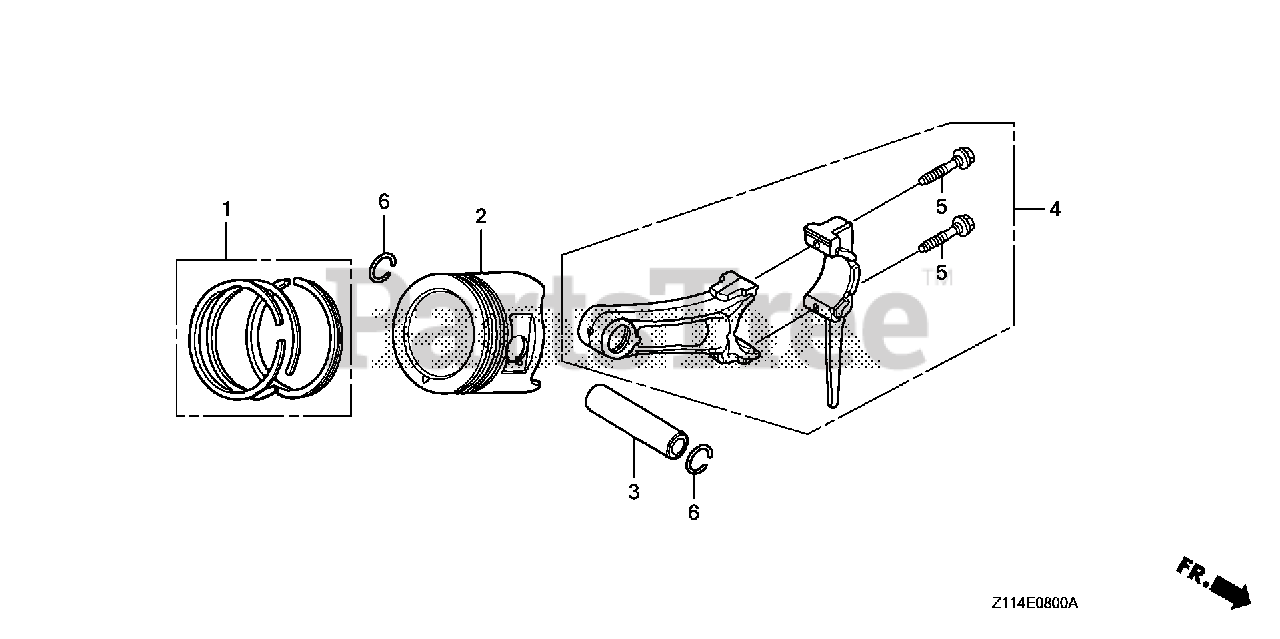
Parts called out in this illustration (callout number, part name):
1	RING SET, PISTON (STD)
1	RING SET, PISTON (STD) (TPR)
1	RING SET, PISTON (OS 0.25)
1	RING SET, PISTON (0.25) (TPR)
1	RING SET, PISTON (OS 0.50)
1	RING SET, PISTON (0.50) (TPR)
1	RING SET, PISTON (0.75)
1	RING SET, PISTON (0.75) (TPR)
2	PISTON (STD)
2	PISTON (OS 0.25)
2	PISTON (0.25)
2	PISTON (OS 0.50)
2	PISTON (0.50)
2	PISTON (OS 0.75)
2	PISTON (0.75)
3	PIN, PISTON
4	ROD ASSY., CONNECTING (US 0.25)
4	ROD ASSY., CONNECTING (STD)
5	BOLT, CONNECTING ROD
6	CLIP, PISTON PIN (20MM)
